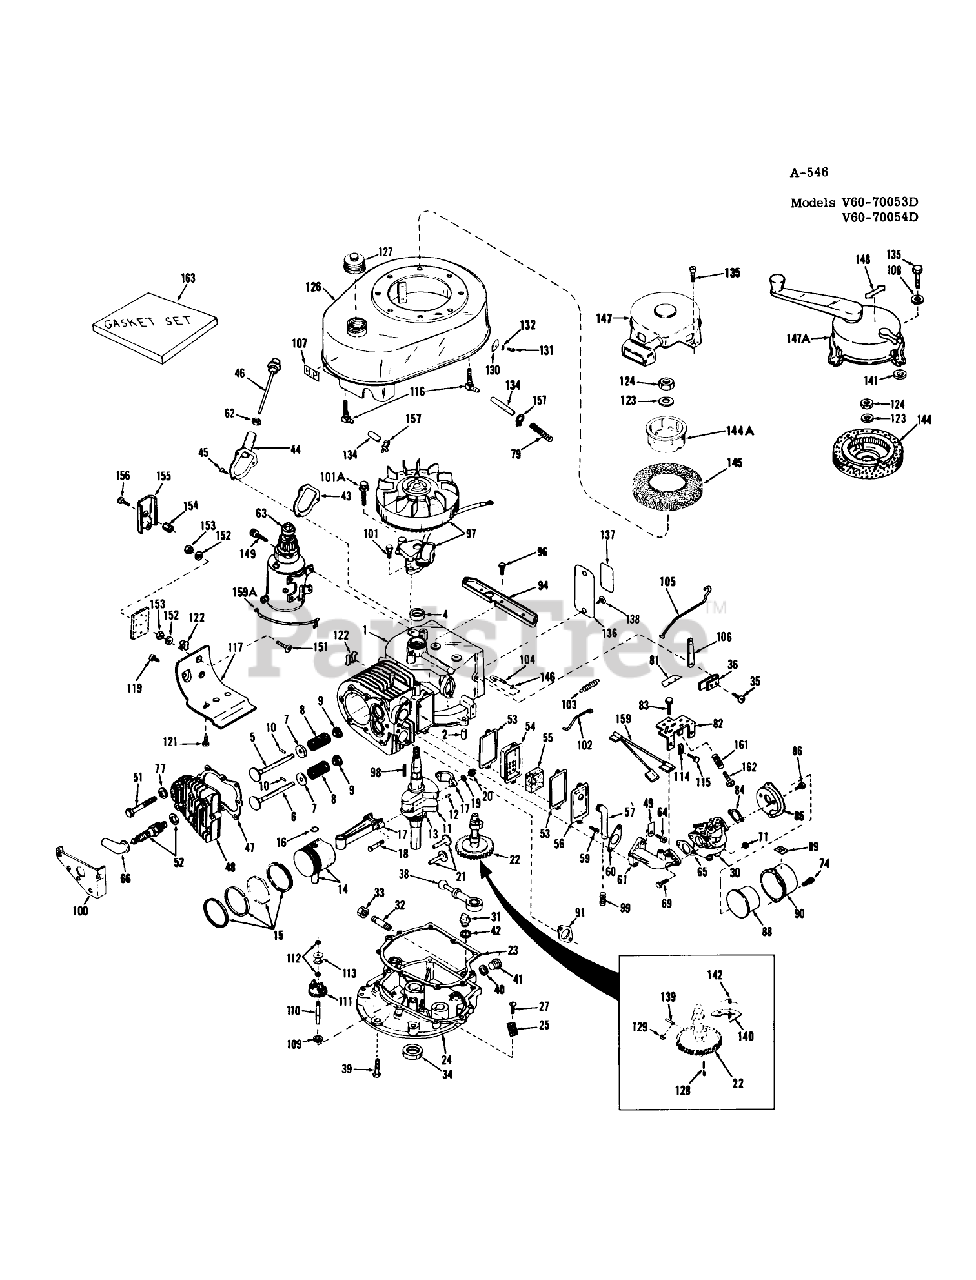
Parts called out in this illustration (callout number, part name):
1	Cylinder Assy.(Incl. Nos. 2 4)
2	Pin-Dowel
4	Seal, Oil
5	33154A,55A,60A W/FO
5	Valve, Intake (1/32" oversize) (Incl. No. 9)
6	Valve, Exhaust (Standard)
6	Valve, Exhaust (1/32"over-size) (Incl. No. 9)
7	Cap-Spring, Valve
8	Spring-Valve
9	Cap, Lower valve spring
9	Cap, Lower Valve Spring (1/32" oversize)
10	Pin, Valve spring retaining
11	Crankshaft Assy. (Incl. Nos. 12 13)
12	Pin, Groove
13	Gear-Crankshaft
14	Piston Pin Assy., Std., (Incl. 2 of No. 16)
14	Piston Pin Assy., .010 oversize (Incl. 2 of No. 16)
14	Piston Pin Assy., .020 oversize (Incl. 2 of No. 16)
15	Ring Set (Standard)
15	Ring Set (.010 Oversize)
15	Ring Set (.020 Oversize)
17	Rod Assy., Connecting (Incl. Nos. 18, 19 20)(Model V60-70073G only)
18	Bolt, Connecting Rod
19	Washer
21	Lifter Valve
22	Screw
23	Gasket-Cover, Cylinder
24	Flange Assy., Mounting (Incl. Nos. 25, 27, 30, 34, 37 110)
25	Screen-Oil Filter
27	Screw
30	Carburetor
31	Plug-Fill, Oil
32	U-Bolt
33	Cap-Pipe
34	Seal-Oil
35	Screw
36	Clamp-Lever, Governor
38	Pump, Oil
39	Screw (1/4-20 x 1-1/4)
40	Gasket-Oil Drain
41	Plug, Drain
42	Gasket
43	Gasket, Filler tube
44	Tube, Oil Filler
45	Screw
46	Dipstick, Oil (Incl. No. 62)
47	Gasket-Head, Cylinder
48	CYLINDER HEAD
49	Clip, Fuel Line
51	Screw
52	SPARK PLUG
53	Gasket-Breather
54	Body-Breather
55	Element-Breather
56	Cover-Valve
57	Tube-Breather
59	Screw
60	Gasket-Intake
61	Pipe, Intake
62	Gasket
63	Motor, Starter
64	Screw (T-30, 5/16-18x1-3/32)
65	Gasket
66	51005 GIL.ROTARY TI
71	Nut and Lock Washer (1/4-28)
74	Screw
77	Washer
79	Spring, Coil
81	Decal
81	Decal, Speed control
82	Control Assy., Speed
83	Screw (10-24 x 9/16)
84	Gasket
85	Bracket
86	Screw (10-32 x 1/2)
88	AIRCLEANER
89	DECAL, AIRCLEANER
90	Body
91	Gasket Exhaust
94	Bracket, Blower Housing (Incl. Nos. 131)
96	Screw (1/4-20x19/32)
97	Magneto
97	Magneto, Tecumseh Alternator (Use with Model V60-70054D only)
98	Key, Flywheel
99	Spring, Coil
100	Cover, Cylinder head
101	Screw
101A	Screw, Hex Hd. Cap, Sems
102	Link, Governor spring
103	Spring Governor
104	Rod, Governor (Incl. Nos. 146)
105	Link Governor
106	Lever-Governor
107	Decal, H. P.
108	Washer
109	Spacer
110	Shaft, Governor
111	Governor Gear ASM
112	Ring-Retaining
113	Spool-Governor
114	Conduit
115	Screw (10-32 x 3/8)
116	Fitting, Fuel Strainer
117	Extension, Blower Housing
119	Screw
121	Screw
122	51004 GIL ROTARY TI
123	Washer
126	Tank Assy., Fuel
127	Cap, Fuel Filler
128	Bevel Gear
129	90 Spring Pin
130	Plate, Securing
131	Screw
132	Lockwasher
134	Line-Fuel
135	Screw
136	IDENTIFICATION PLATE
137	480B GIL SNWTHWR O/
138	Stud
139	Plunger, Compression Rel.
140	Screw
141	Washer, Flat (Use with Model V60-70053D only)
142	Spring, Yoke
144	Hub Screen
144A	Cup-Starter
145	Screen, Air
146	Washer-Flat
147	Starter, Rewind
147A	Starter, Impulse (Use with Model V60-70053D only)
148	Decal, Starter (Use with Model V60-70053D only)
149	Screw
151	56008 ADN.KIT 28727
152	Lockwasher (Model V70-125149)
153	33144C/45C/49A/53A
154	Nut, Long (Model V70-125149)
155	Cover, Panel
156	Screw
157	Clamp-Line, Fuel
159	Wire, Ground (Use with Model V60-70053D only)
159A	Wire, Ground
161	Spring-Compression
162	Screw
163	Gasket Set
